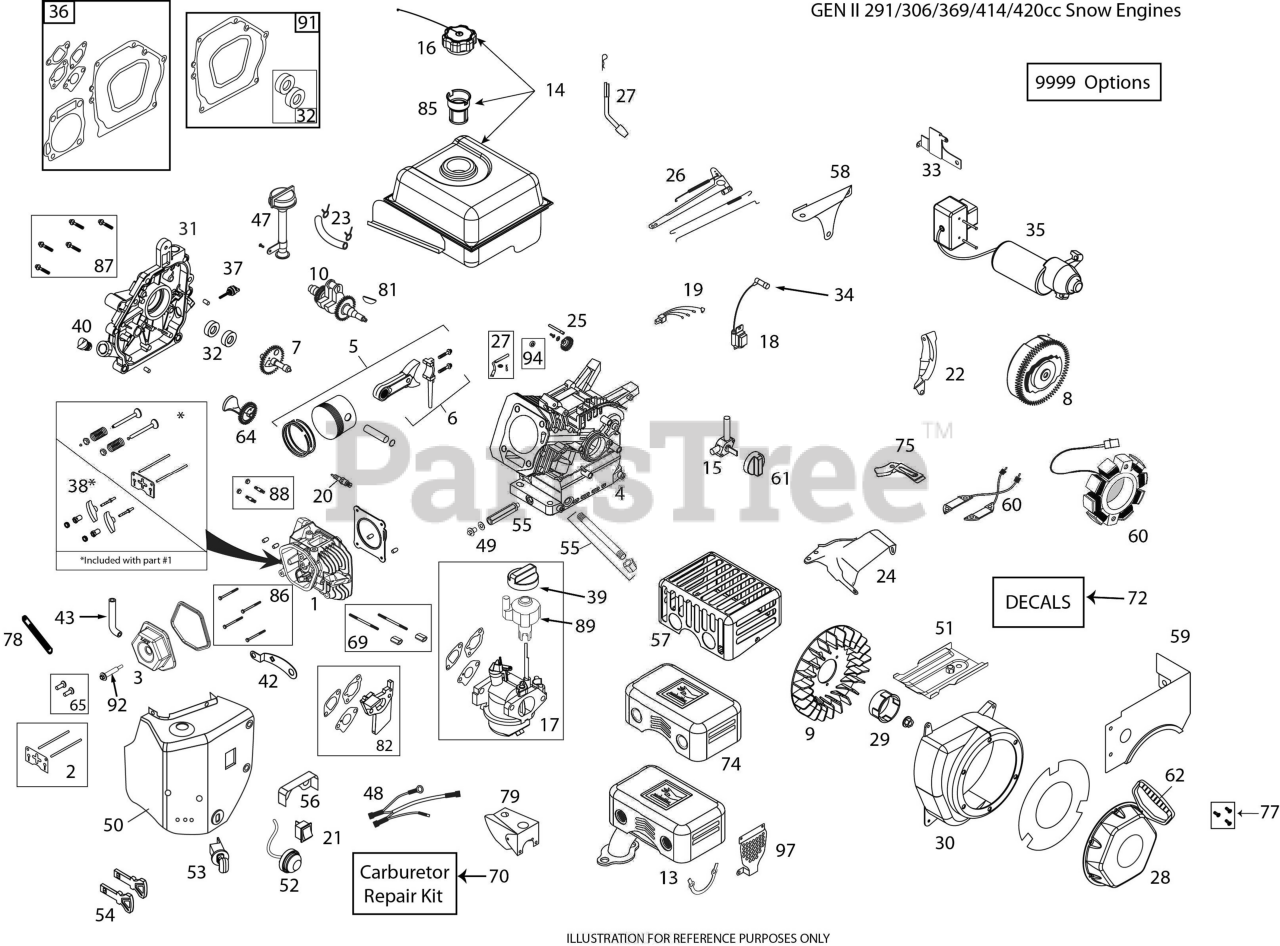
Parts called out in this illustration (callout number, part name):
1	CYLINDER HEAD LCT 178 INCLUDES
2	PUSH ROD TAPPET KIT
3	VALVE.COVER.LCT.414CC.
5	PISTON ROD ASM.LCT SK3691400.1
7	CAMSHAFT(SK4141600)
8	FLYWHEEL.EL.ST.SKSN4408.1
9	FLYWHEEL.FAN(SK4144000)
10	CRANKSHAFT KEYED #18 LCT 414C
13	MUFFLER.ASSY.SNOW(SKSN4200)
14	FUEL.TANK.ASSY.SNOW(SKSN4300)
15	FUEL.PETCOCK.SNOW(SKSN4900)
16	FUEL CAP OVERSIZED CLICK STYLE
17	CARBURETTOR L18D LCT 369
18	IGNITION.COIL.(CDI).291-414CC
20	SPARK.PLUG(SK2911550)
21	ON/OFF.SWITCH.SNOW(SKSN4403)
23	FUEL HOSE KIT
24	CONTROL.SPEED.FIXED.LCT.SKSN44
25	GOVERNOR.GEAR.ASSY(SK4142900)
26	GOVERNOR.ARM.ASSY(SKSN4502)
27	GOVERNOR.SHAFT(SK4143100)
28	RECOIL.START.ASSY.SNW(SKSN4600
29	STARTER.CUP.SML.SNOW(SKSN4601)
30	BLOWER HOUSING.LCT 369 GLOSS
31	CRANKCASE.COVER.LCT.414CC.HIGH
32	OIL SEAL KIT NON-GENERATOR
33	ELECTRIC.START.BRKT(SKSN4405)
34	SPARK.PLUG.BOOT.SNW,SKSN4691.1
35	STARTER EUROPEAN 230V ELECTRIC
36	GASKET KIT ENGINE LCT 369
37	DIPSTK.OIL.BLK.LCTSK4143711.1
38	ROCKER ARM KIT
39	CHOKE.KNOW.SNOW(SKSN4500)
40	NONREMVABLE.OIL.PLUG(SK4143715
43	BREATHER TUBE LCT 291/369/414
47	HIGHOIL.FILL.ASSY.KIT(SKSN4911
48	WIRE.HARNESS.SNOW
49	OIL.DRAIN.PLUG
50	HEATER.BOX.ASSY-SNW(SKSN4100)
51	SHIELD.CYLINDER.SNOW(SK4141010
52	PRIMER.BULB.ASSY(SKSN4304)
53	KEY.SWITCH.ASSY.SNOW(SKSN4401)
54	KEY SET(2 KEYS) SKSN0407.1
55	OIL PIPE DRAIN EXTENDED.LCT SK
56	SHIELD.VAPOR(SKSN4606)
57	CE COMPLIANT MUFFLER SHEILD
58	PLATE.GOVERN.LINK.S
59	SKIRT FUEL TANK
60	ALTERN.60WATT.SKSN2402.1
61	FUEL KNOB-SNOW
62	STARTER.GRIP.SNOW.LCT.SKSN0603
64	COUNTER WEIGHT KIT
65	TAPPET KIT.LCT.SK2911005.1
69	STUD.CARB.MOUTING.KIT.414CC
70	CARBURETTOR REPAIR KIT 291CC/4
74	MUFFLER SHIELD
75	SHIELD.U/FYWHL.CHARG(SKSN4604)
77	BOLT.KIT.RECOIL.LCT.ALL.ENGINE
78	STRAP.RETAINING.TUBE.BREATHER.
79	SHIELD CARBURRETOR COVER 414
81	KEYS.FLYWHEEL.208/414CC.5PACK
82	SPACER.CARBURETOR.414CC.LCT
85	STRAINER.FUEL.TANK.LCT.208CC
86	KIT.BOLT.CYLINDER.HEAD.(4PC)
87	KIT.BOLT.CRANKCASE.COVER.414CC
88	STUD.MUFFLER.KIT.LCT
89	KNOB LCT.SKSN5325.1 SPEED
91	GASKET KIT CRANKSHAFT.LCT
92	CENTER VALVE COVER BOLT
94	SEAL GOVERNOR SHAFT OIL.LCT
97	GUARD.EXHAUST
9999	KIT.BOLT.LCT.SK9990.1
9999	STARTER SCREW.STARTER SWITCH B
9999	HIGH ALTITUDE JET 6000FT
